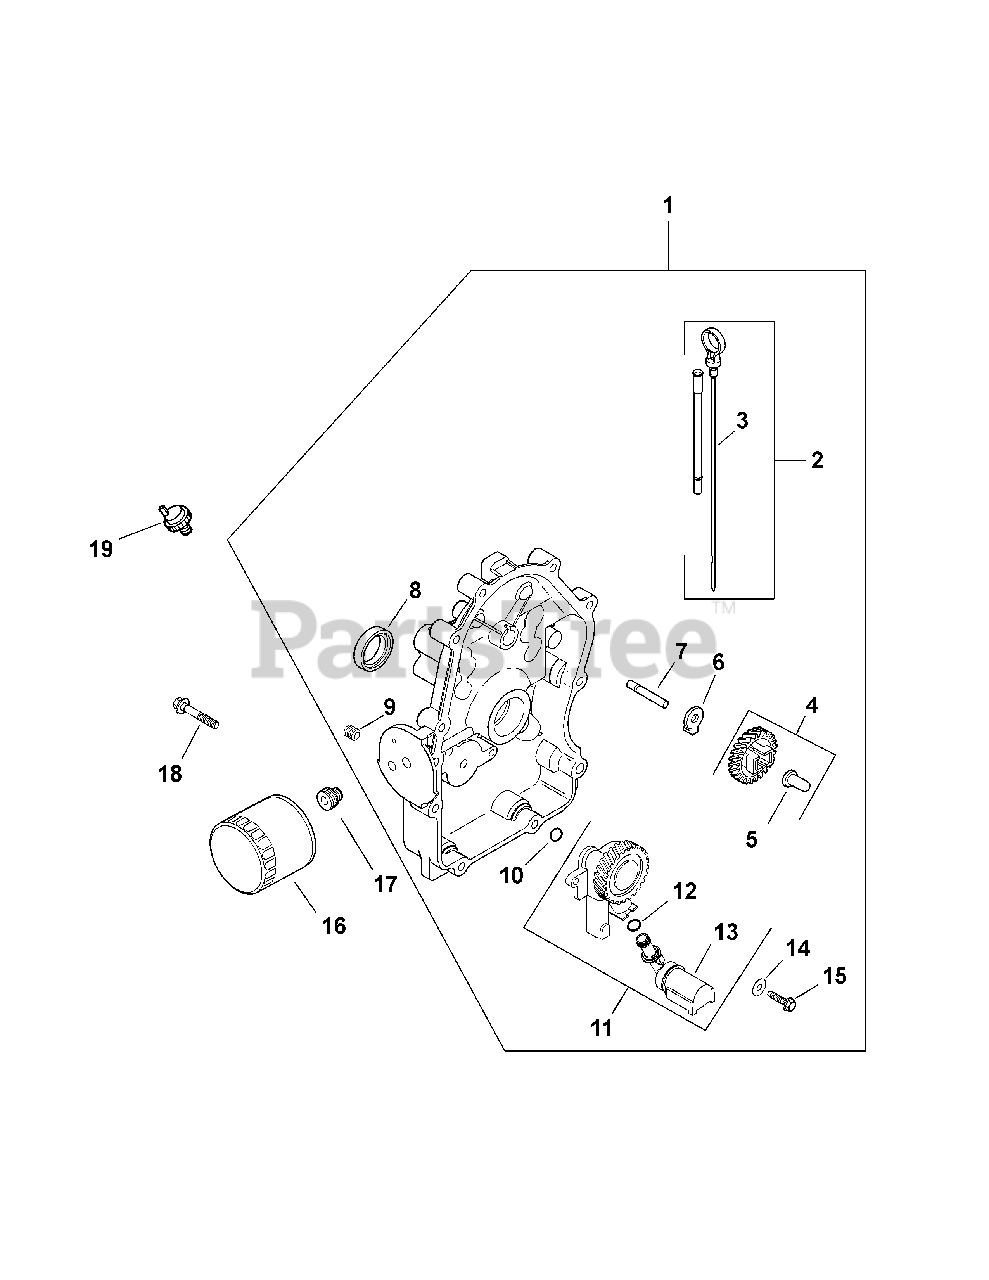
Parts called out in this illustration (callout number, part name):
1	CLOSURE PLATE ASSEMBLY
2	KIT, DIPSTICK/DIPSTICK TUBES
4	KIT, GOVERNOR GEAR W/PIN
5	PIN, GOVERNOR REGULATING
7	SHAFT, GOVERNOR GEAR
9	PLUG, CTSK PIPE 1/8"
11	KIT, OIL PUMP ASSEMBLY
12	O-RING, OIL PICK-UP
13	PICK-UP, OIL
14	WASHER, FLAT 6 MM
15	SCREW, FLG THD FRM M6X1.0X25
17	NIPPLE, OIL FILTER
18	SCREW, FLG M8X1.25X45
19	SWITCH, OIL PRESSURE
